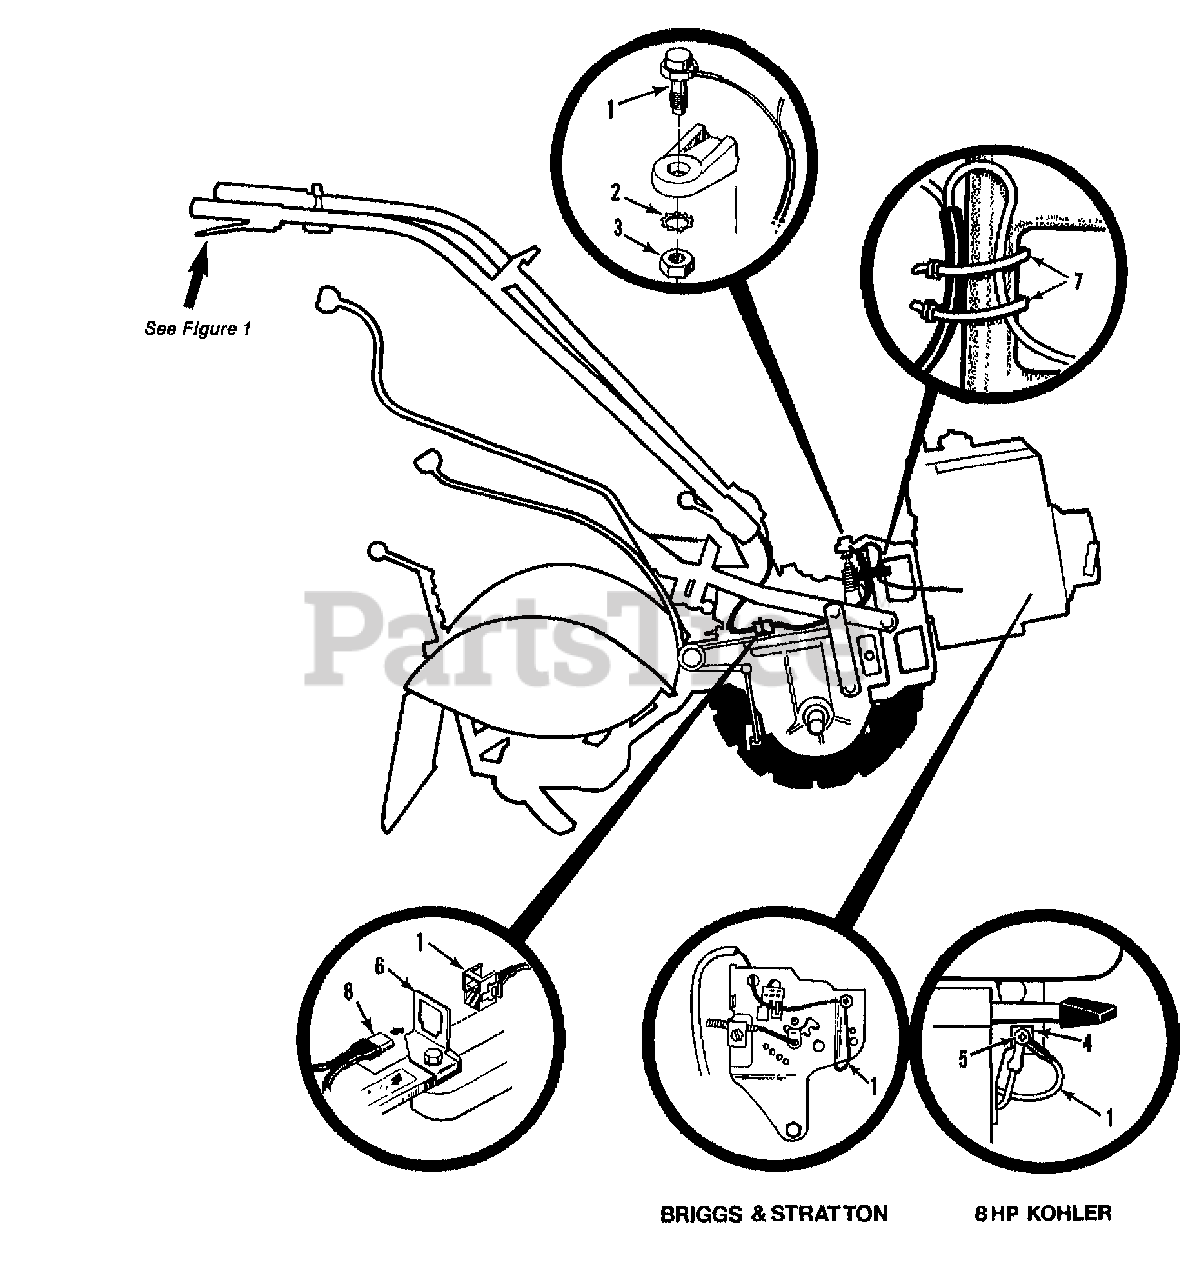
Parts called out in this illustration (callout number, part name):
1	HARNESS-WIRE ENG OPC
2	WASHER-LK .438 EXT TOOTH
3	NUT-HEX/JAM 7/16-20
4	GROMMET-7 T/L & 8 KOH OPC
5	SCR #8-18 SELF TAP
6	CLIP-CONNECTOR
7	TIE-RED
8	HARNESS-WIRE OPC HORSE
